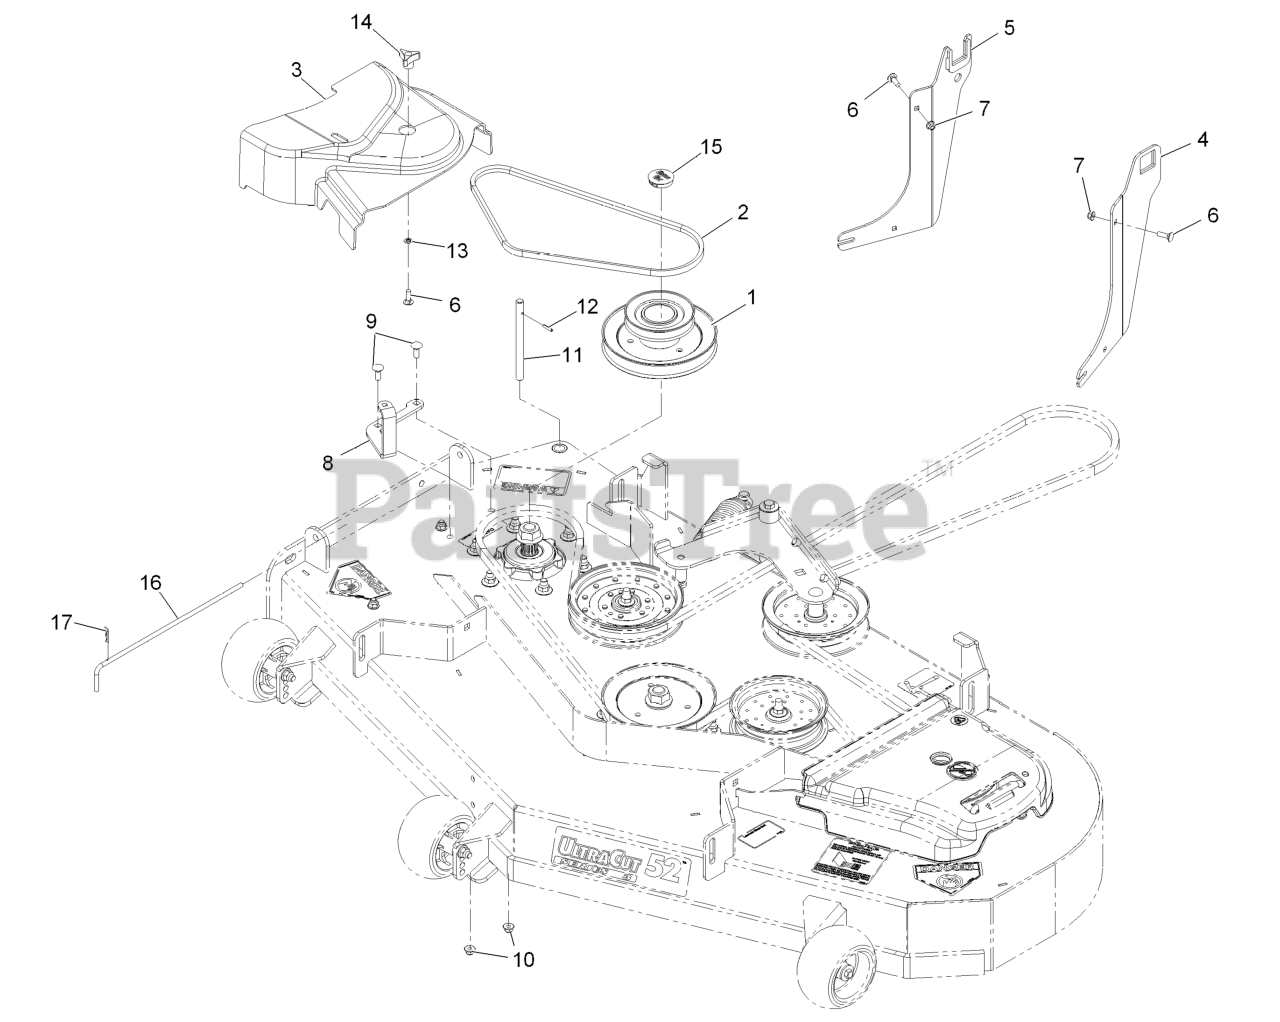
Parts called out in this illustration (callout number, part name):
1	JACKSHAFT,UV DRIVE 524 SP
2	BELT-BLOWER
3	COVER-BELT, UV 52
4	BRACKET ASM, LH
5	BRACKET ASM, RH
6	BOLT-CARR
7	NUT-HF, NI
9	BOLT-CARR
10	NUT-HF, NI
11	SHAFT-CATCHER, GRASS
12	PIN-ROLL
13	RING-RETAINING, BOLT
14	KNOB-3 PRONG
15	PLUG, BLACK NYLON 1.75
16	PIN,CHUTE PIVOT
17	PIN-COTTER
